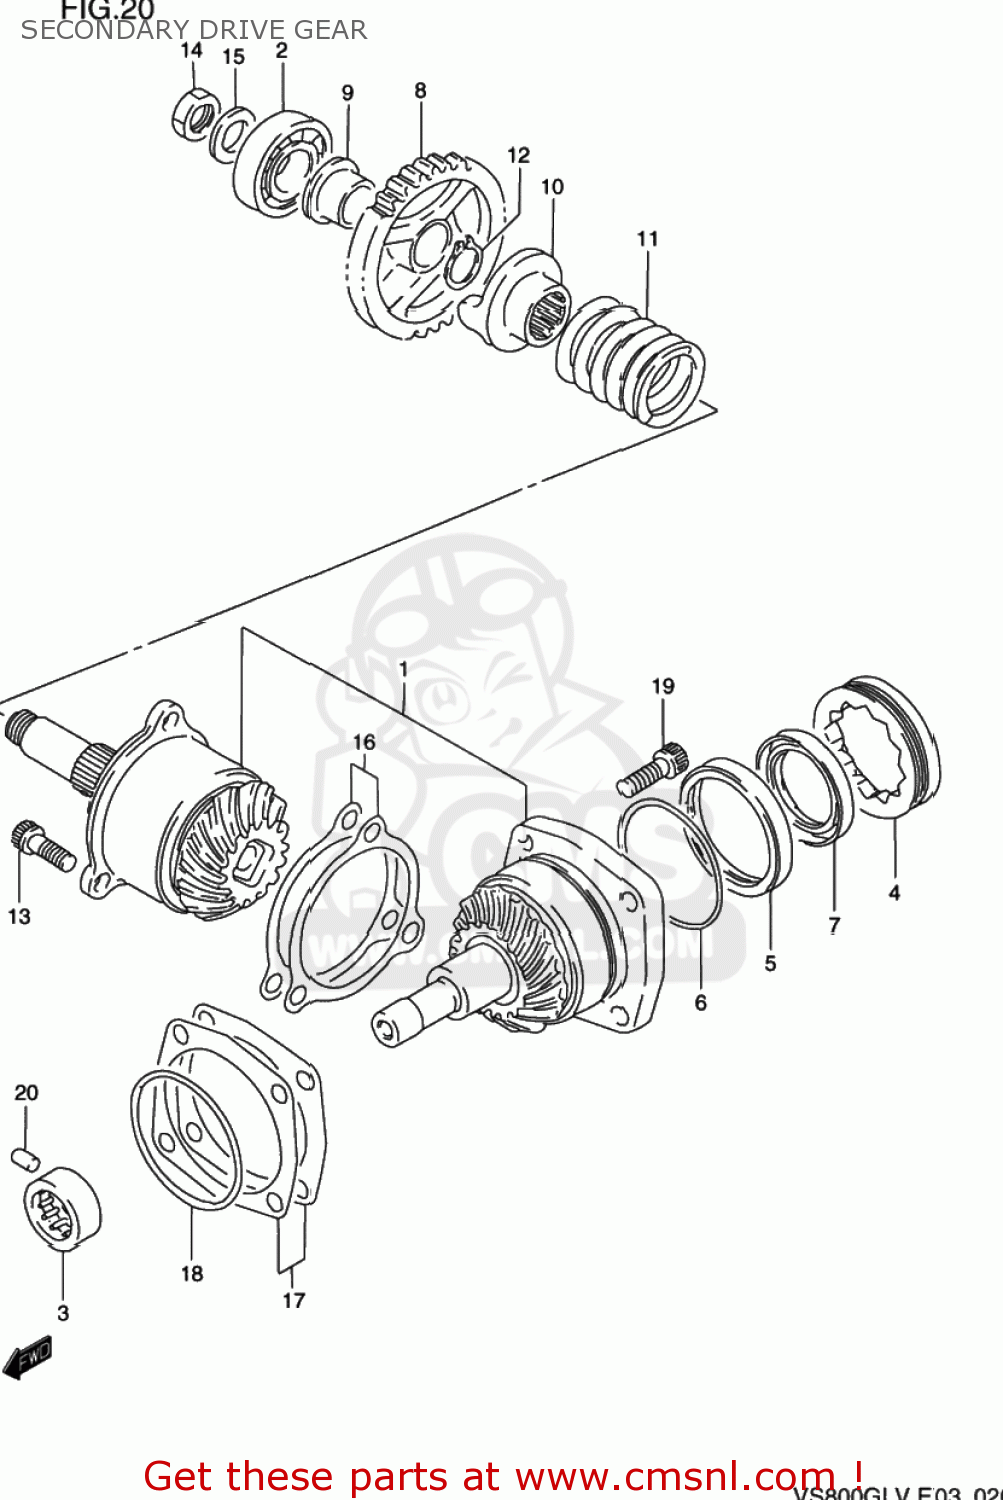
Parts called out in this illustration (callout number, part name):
1	GEAR & HOUSING SET,SECONDARY
2	BEARING(20X52X15)
3	BEARING(20X34X16)
4	STOPPER,SEC DRIVEN BEARING
5	HOUSING,OIL SEAL
6	O RING(D:1.2,ID:59.6)
7	SEAL,OIL(38X54X8.5)
8	GEAR,REDUCTION DRIVEN(NT:30)
9	BUSH,REDUCTION DRIVEN GEAR
10	DOG,OUTPUT CAM
11	SPRING
12	CIRCLIP
13	BOLT
14	NUT
15	WASHER(16X29X4)
16	SHIM SET,SEC DRIVE GEAR
17	SHIM SET,SEC DRIVEN HOUSING
18	O RING(D:2.1,ID:66.2)
19	BOLT
20	PIN
